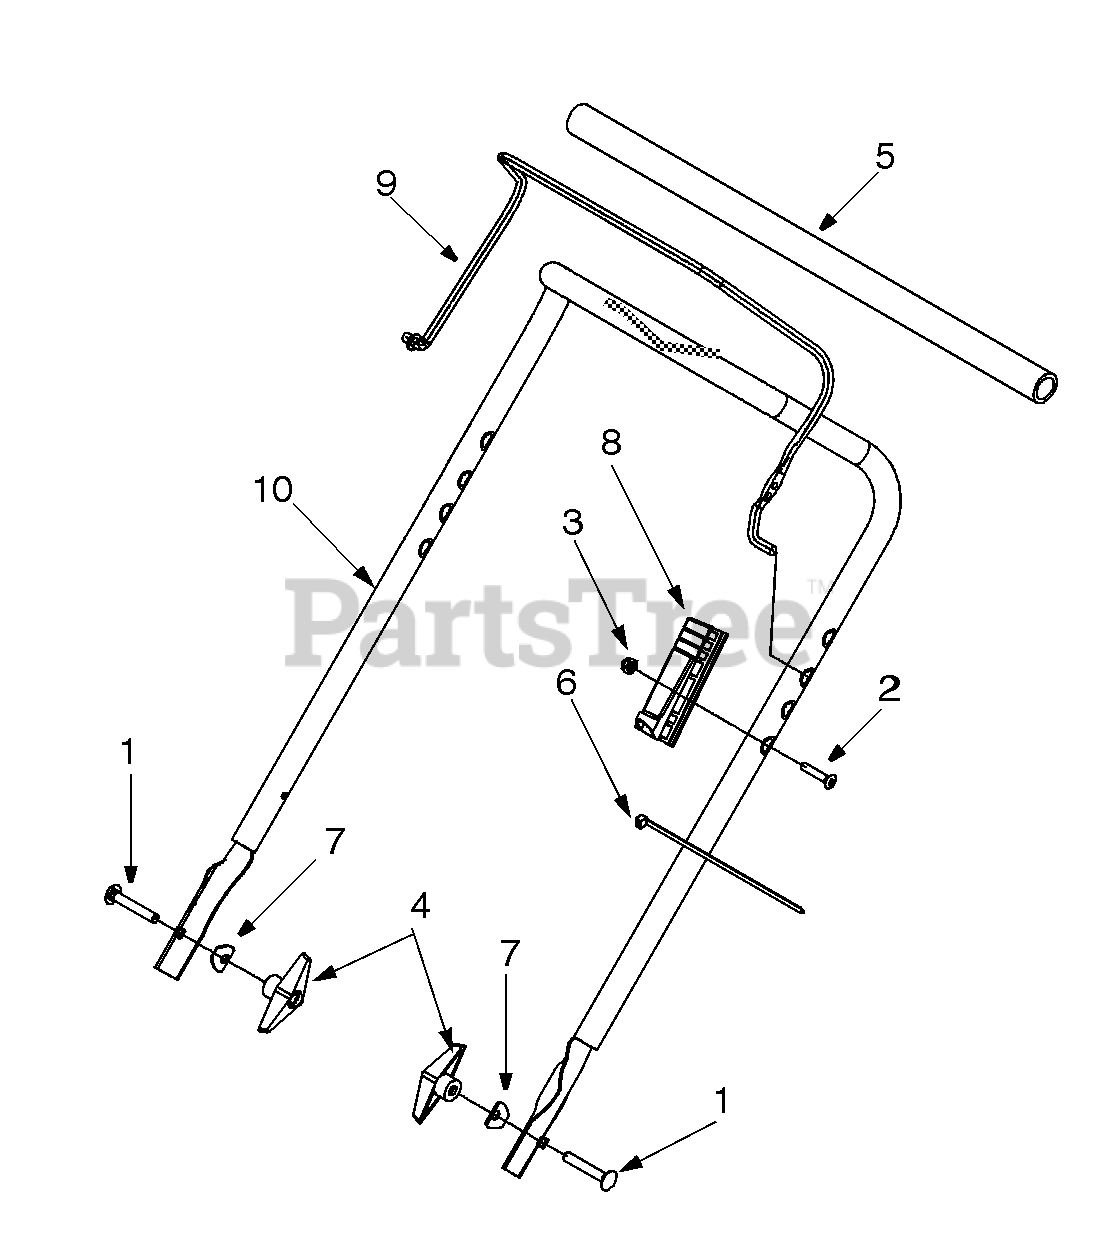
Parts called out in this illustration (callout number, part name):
1	Carriage Screw 5/16-18 x 2.0
2	Oval C-Sunk Screw 1/4-20 x 1.31
3	Hex Lock Nut 1/4-20
4	Handle Knob
5	Foam Grip: Handle
6	Cable Tie
7	Saddle Washer
8	Cable Housing
